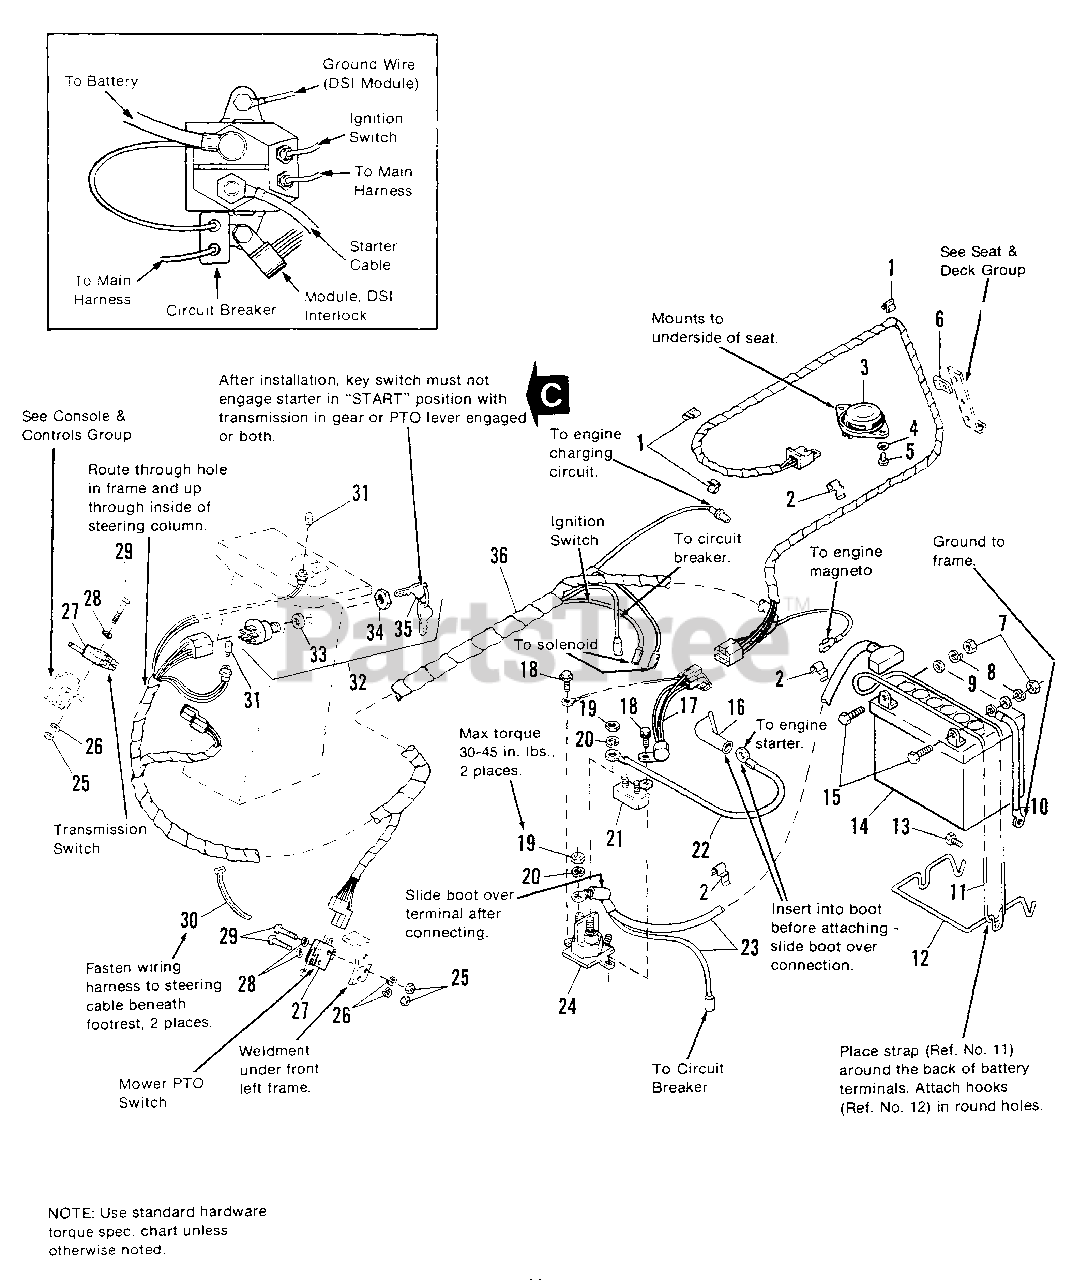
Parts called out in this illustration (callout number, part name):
1	CLIP, Wire
3	SWITCH, Seat
4	LOCKWASHER, Ext., 1/4
5	SCREW, Rd. Hd., 1/4-20 x 1/2
6	CLAMP, Wire
7	NUT, Hex, 1/4-20
8	LOCKWASHER, 1/4
9	WASHER, 1/4
10	CABLE ASSY. (Battery Ground)
11	STRAP, Battery
12	BRACE, Battery Hold Down
13	SCREW, Taptite, 5/16 x 1/2 (Zinc Pltd.)
14	BATTERY, 12V
15	CAP SCREW, Hex, 1/4-20 x 3/4)
16	COVER, Terminal
17	MODULE, DSI, Interlock
18	SCREW, Taptite, 1/4-20 x 3/4, Pltd.
19	NUT, Hex, 5/16-24
20	LOCKWASHER, 5/16
21	CIRCUIT BREAKER
22	CABLE ASSY., Starter
23	CABLE ASSY., (Battery Solenoid)
24	SOLENOID
25	NUT, Hex, #5-40
26	LOCKWASHER, #5
27	MICRO SWITCH, Tandem
28	WASHER, #6
29	SCREW, Rnd. Hd., #5-40 x 1-1/2
30	CABLE TY-WRAP
31	LAMP, Indicator
32	SWITCH, Ignition (Incl. Ref. Nos. 33, 34 & 35.)
33	LOCKWASHER, Int. 5/8
34	NUT, 5/8-32
35	KEYS & RING
36	WIRING HARNESS
